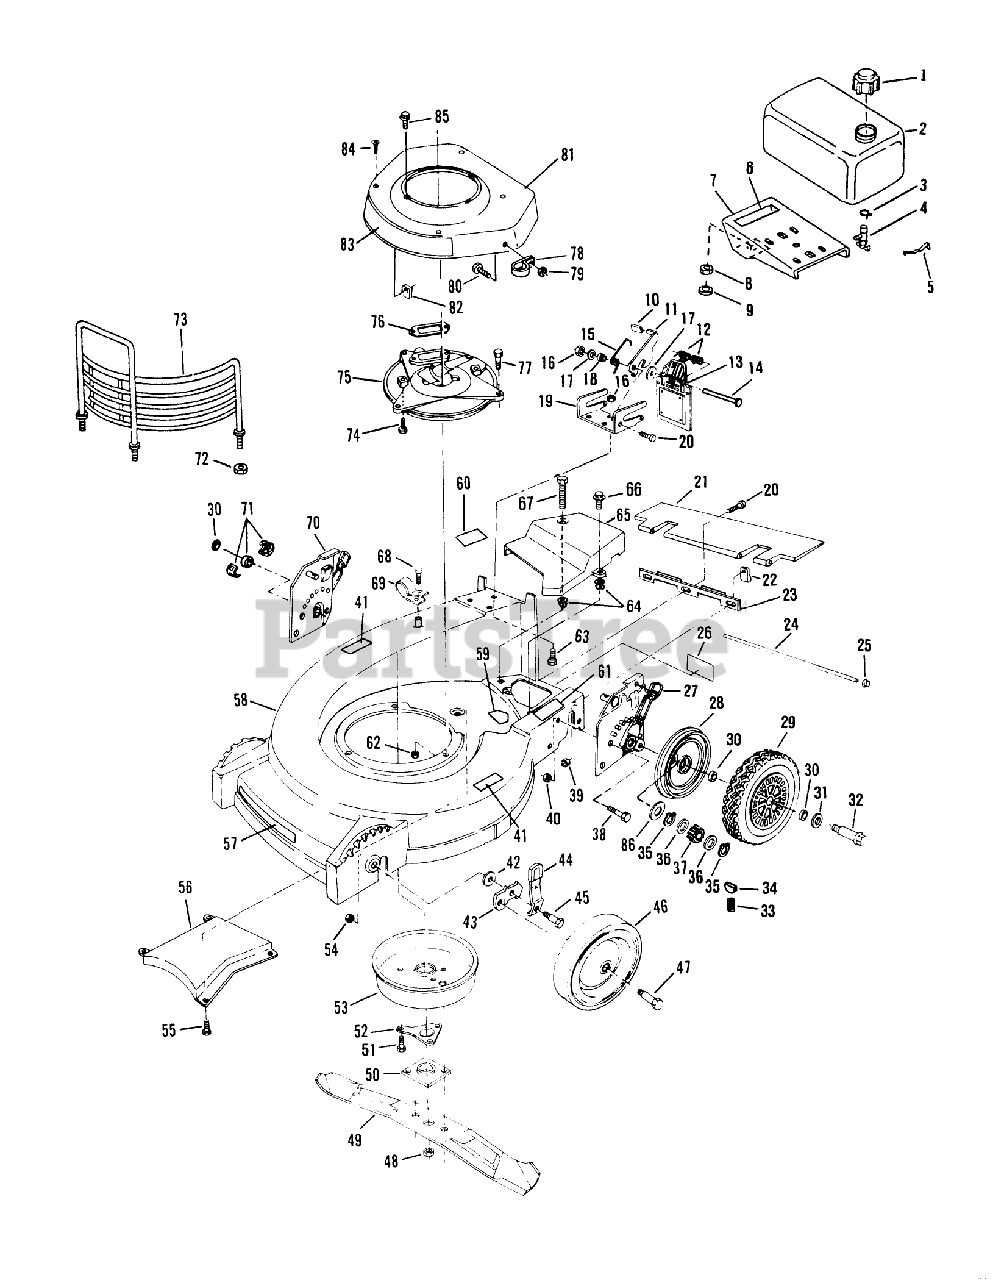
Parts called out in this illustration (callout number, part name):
1	FUEL CAP & INSERT
3	CLAMP - HOSE S
4	VALVE&SCREEN SM
5	SPRING
7	BRACKET - TANK
8	LOCKNUT E
9	WASHER
10	KNOB (S&R)
12	SPRING ASOC
14	ROD (RB&W)
15	SPRING
16	LOCKNUT E
21	T/SHIELD SM&P
30	WASHER
31	SPACER
33	SPRING
34	KEY
35	RET RING
36	SPACER/GR ALGHNY
37	PINION BROCKWAY
39	LOCKNUT E
40	NUT-LOCK F
42	WASHER
44	SPRING ARM ASM
45	BOLT
46	WHEEL/TIRE ASM
47	BOLT-SHOULDER
48	NUT-BLADE
50	PLATE AND COLLAR ASM
51	SCREW
52	SUPPORT F
53	MUFFLER COVER F
54	LOCKNUT
56	BAFFLE CHUTE PL
58	HSG-20" SP
62	NUT-LOCK F
63	SCREW
66	SCREW
68	SCREW LAWRENCE
71	REAR AXLE BEARING
72	NUT-LOCK F
74	SCREW V
75	M/PLATE
77	SCREW-HH
79	LOCKNUT E
82	PUSHNUT F
84	SCREW - SELF TAPPING
85	SCREW SEMS SM
86	THRUST WASHER
